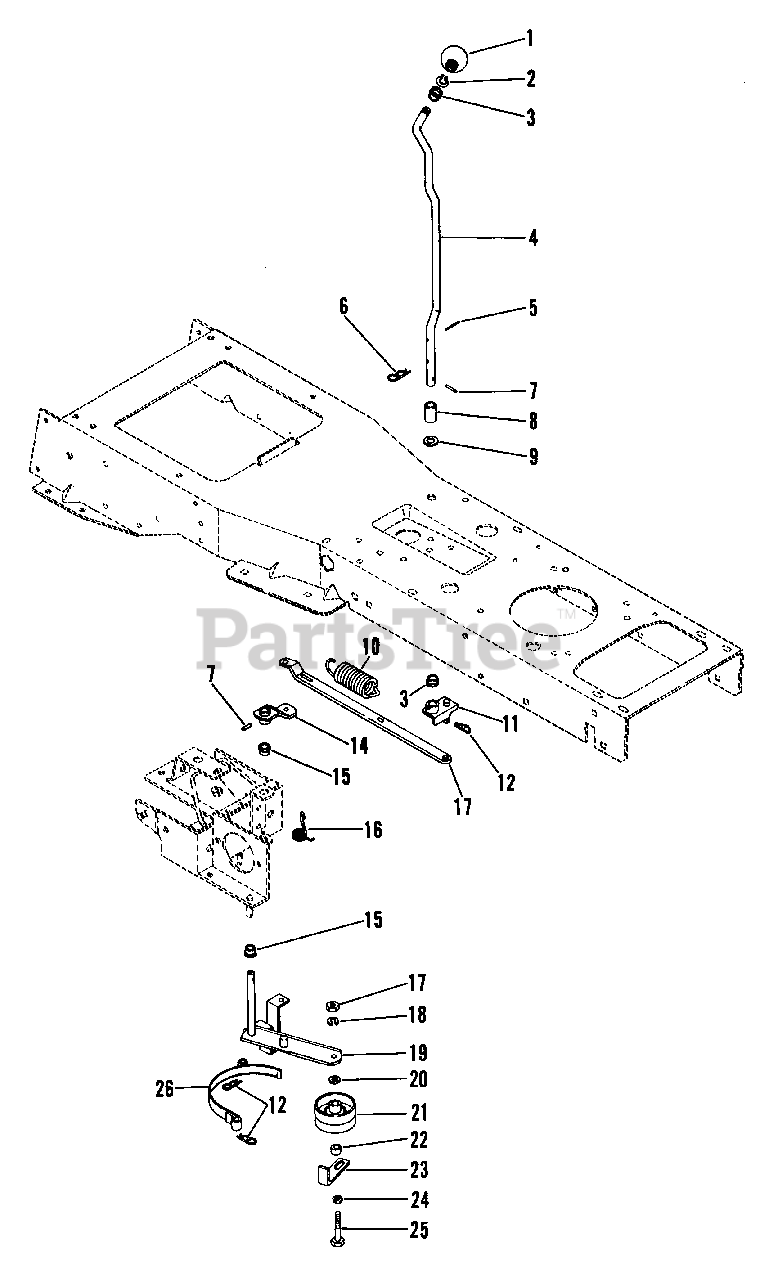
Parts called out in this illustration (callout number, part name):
1	PTO BALL
2	RG-RTNG-EXT .500X.050
3	BSHG-FLG.500X.625X.312X.750NY
4	PTO HANDLE
5	PIN-ROLL .188X1.00
6	PIN-HAIR INT .08X.38X1.42 YWZC
7	PIN-ROLL .188X.75
8	SPACER .75 X .50 X 1.25
9	WSHR-FL-STL .641X1.125X.188
10	SG-TENS .188X1.5X4.75 WLD 105
11	CLUTCH LEVER
12	PIN-HAIR INT .08X.18X1.18
13	CLUTCH LINK PTO
14	IDLER LINK
15	BSHG-FLG .500X.625X.500X.750
16	SG-TORS .090X.62X.350
17	NUT-HEX .375-16
18	WSHR-LK .375X.115 HVY PL
19	IDLER ARM
20	WSHR-FL-STL .382X.812X.062
21	IDLER-FLAT 3.25 X .38 NWHAMSHR
22	BSHG-SLV .437X.625X.500 SB
23	BELT FINGER
24	WSHR-FL-STL.406X.812X.065PL
25	BLT-HEX .38-16X2.50 PL GR2
26	BELT RETAINER
